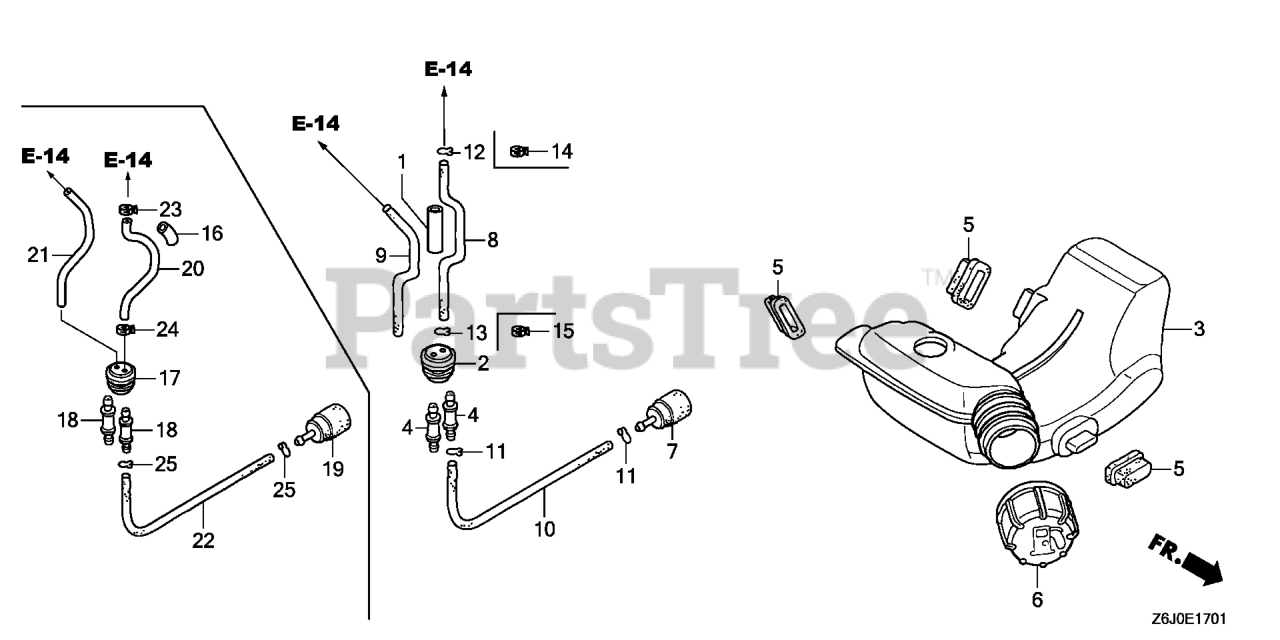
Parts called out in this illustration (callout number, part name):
3	TANK, FUEL
5	RUBBER, TANK MOUNTING
6	CAP ASSY., FUEL TANK
16	PROTECTOR, TUBE
17	GROMMET, FUEL TUBE
18	JOINT, FUEL TANK
19	FILTER, FUEL
20	TUBE, FUEL
21	TUBE, FUEL RETURN
22	TUBE A, FUEL
23	CLAMP, TUBE
24	CLAMP, TUBE
25	CLIP, TUBE (B1 5)
